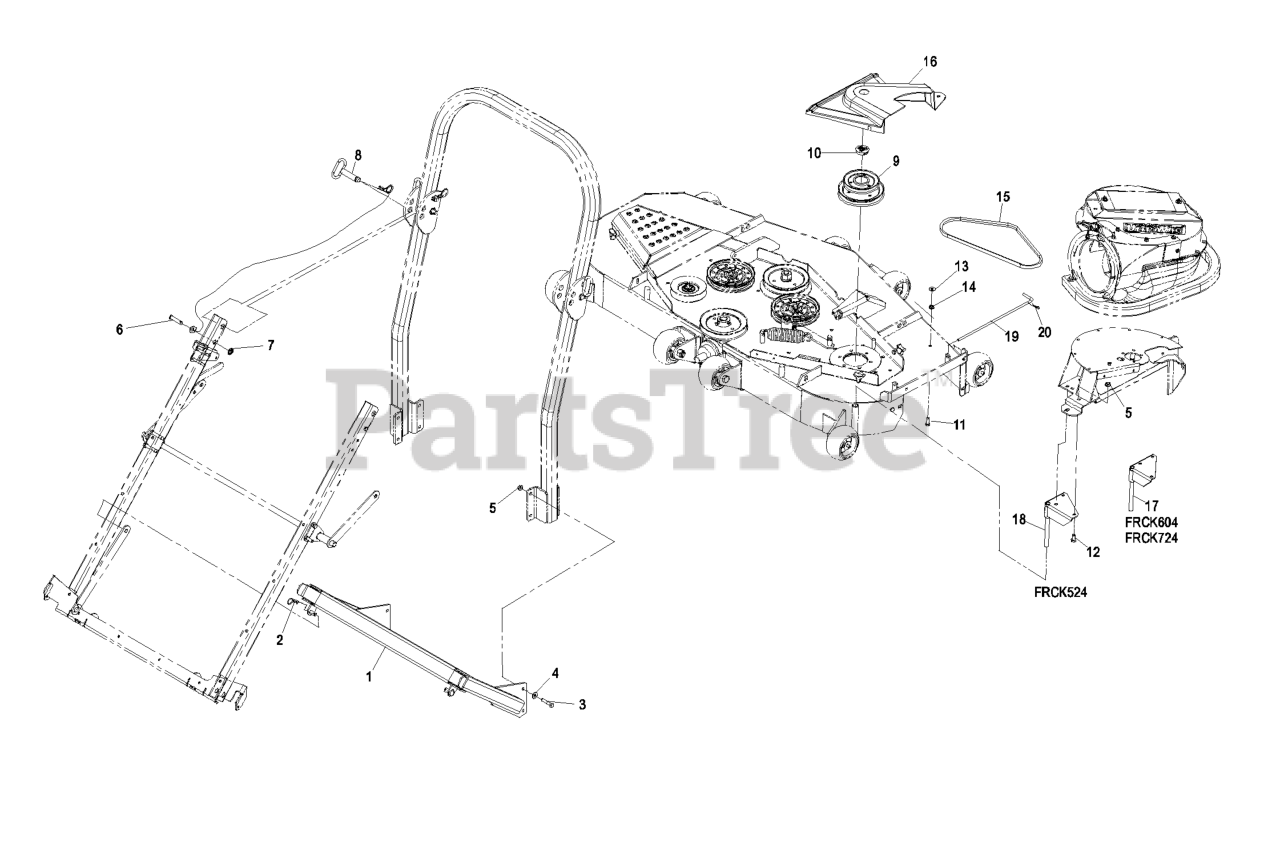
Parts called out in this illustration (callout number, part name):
2	PIN-COTTER
3	SCREW-HH
4	WASHER-BELLEVILLE
5	NUT-HHF, WHIZ
6	PIN-CLEVIS
7	NUT-PUSH
8	PIN-FOLD, ROPS
9	JACKSHAFT, LZUV52
10	PLUG, BLACK NYLON 1.75
11	SCREW-HH
12	SCREW-HH
13	WASHER-FLAT
15	BELT,4L SECTION
16	COVER,FR UV BELT 52
17	PIN-MOUNT
18	WLD,MOUNT PIN FR 52
19	PIN,CHUTE PIVOT
20	PIN-COTTER
